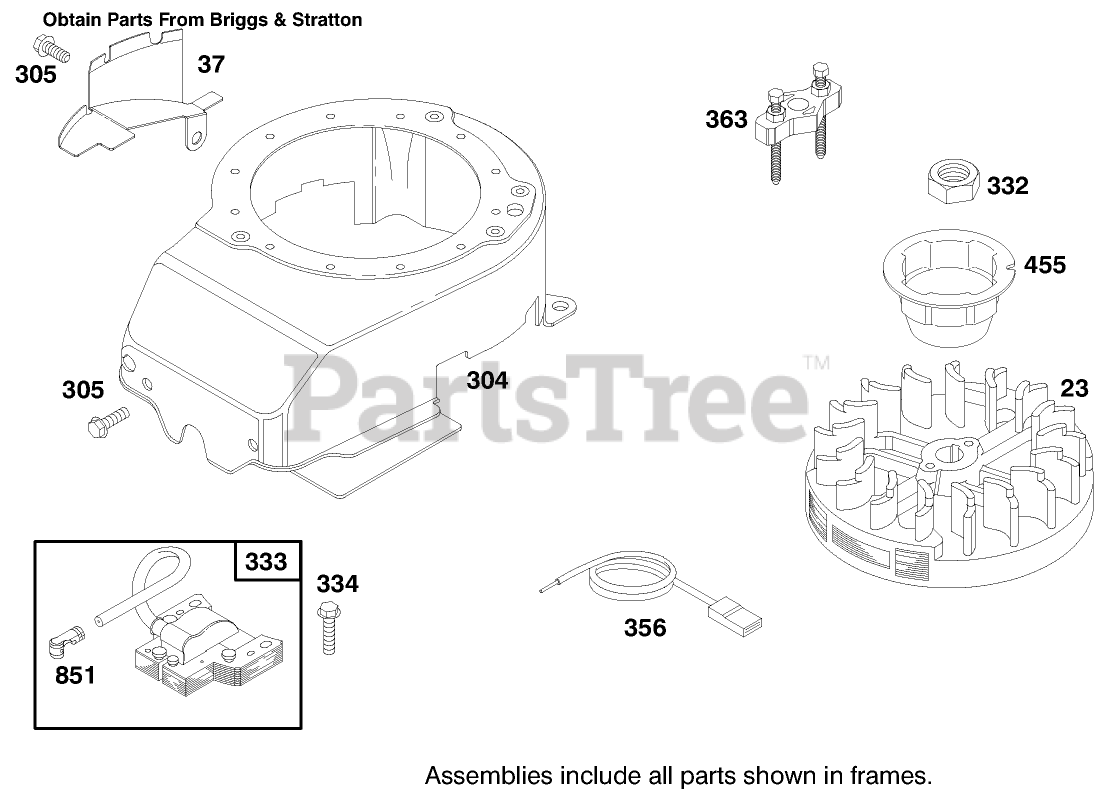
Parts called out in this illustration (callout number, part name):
23	Flywheel
37	Flywheel Guard
304	Housing-Blower
305	Screw-Hex
333	Armature-Magneto
334	Screw-Sem
356	Wire Stop
363	Puller-Flywheel
851	Terminal-Spark Plug
